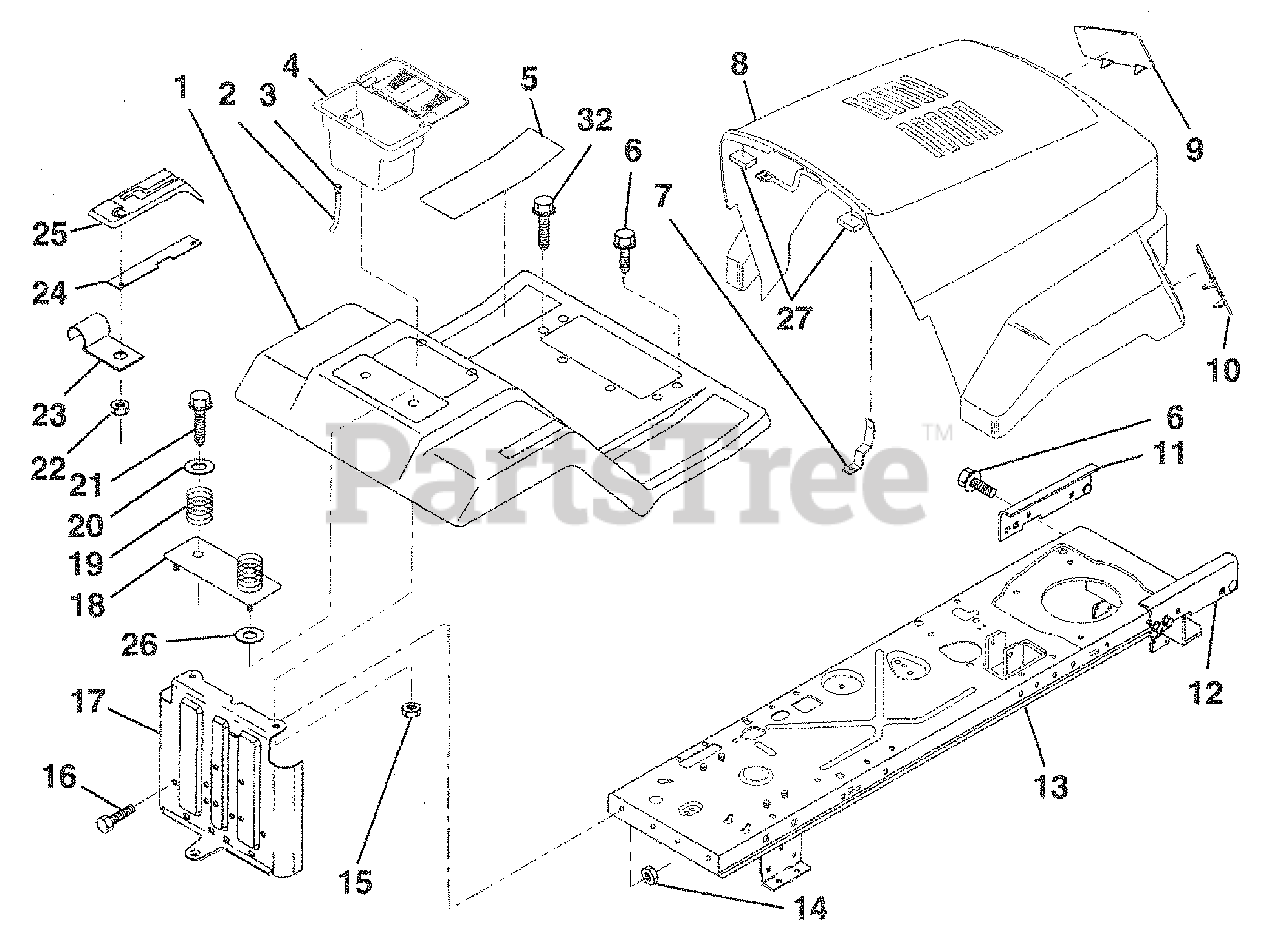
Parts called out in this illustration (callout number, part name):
1	Fender/Footrest
2	Tube, Battery Drain
3	Clamp, Hose
4	Case, Battery
5	Pad, Footrest
6	Screw, Hex Wsh. Thrdrol. 5/16-18 x 3/4
7	Latch, Hood
8	Hood/Grill Asm
9	Lens, L.H.
10	Lens, R.H.
11	Bracket, Asm. Pivot Frame, L.H.
12	Bracket, Asm. Pivot Frame, R.H.
13	Assembly, Frame
14	Nut, Crownlock 5/16-18
15	Nut, Keps, Hex 1/4-20 UNC
16	Bolt, Hex Hd. 5/16-18 UNC x 3/4
18	Plate, Asm. Battery
19	Spring, Compression, Seat
20	Washer 13/32 x 1-1/4 x 12 Ga.
21	Screw Self Tapping
22	Nut, Self-Threading, Washer Head 3/16
23	Clip, Insulated
24	Bar, Shift Lock
25	Console, Shift Control
26	Washer 9/32 x 7/8 x 13 Ga.
27	Bumper, Hood
32	Screw, Hex, Wsh Thd Rol 5/16-18 x 1
